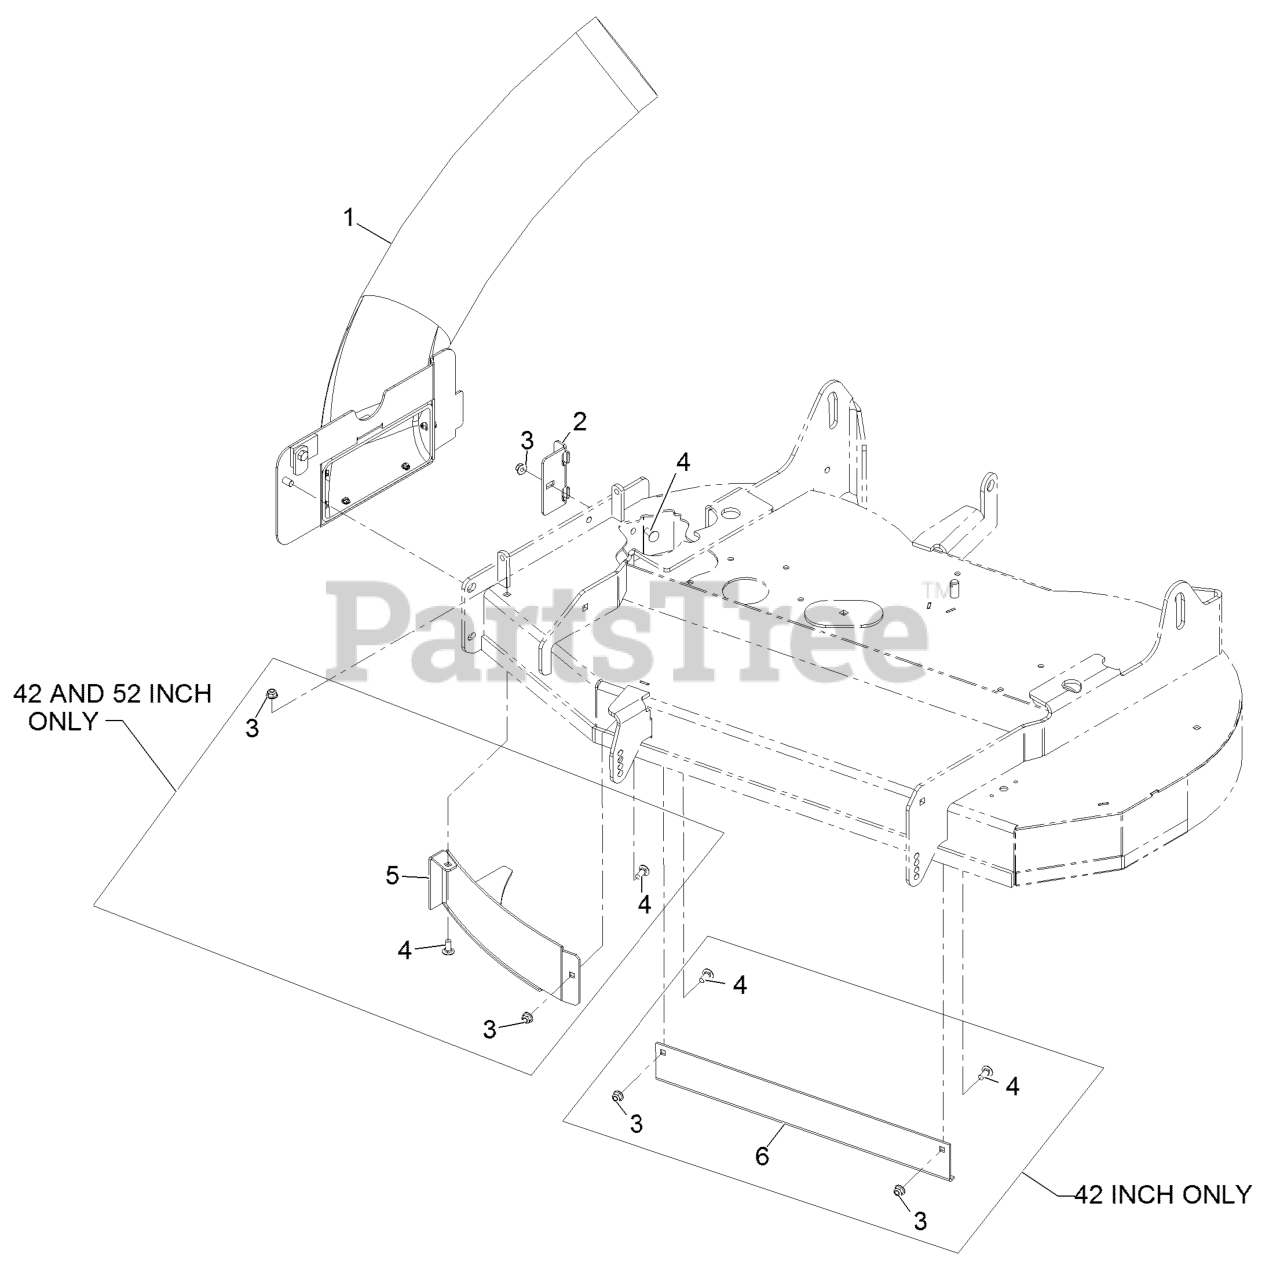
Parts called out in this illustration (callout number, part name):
1	ASM,TUBE AND FRAME
2	BRACKET-BOOT MOUNT, 52 IN
2	BRACKET-BOOT MOUNT, 48 IN
2	BRACKET,42 BAGGER MOUNT
3	NUT-HF, NI
4	SCREW-CARR
5	WLD,DISCHARGE BAFFLE
6	BAFFLE,CENTER BAGGER
